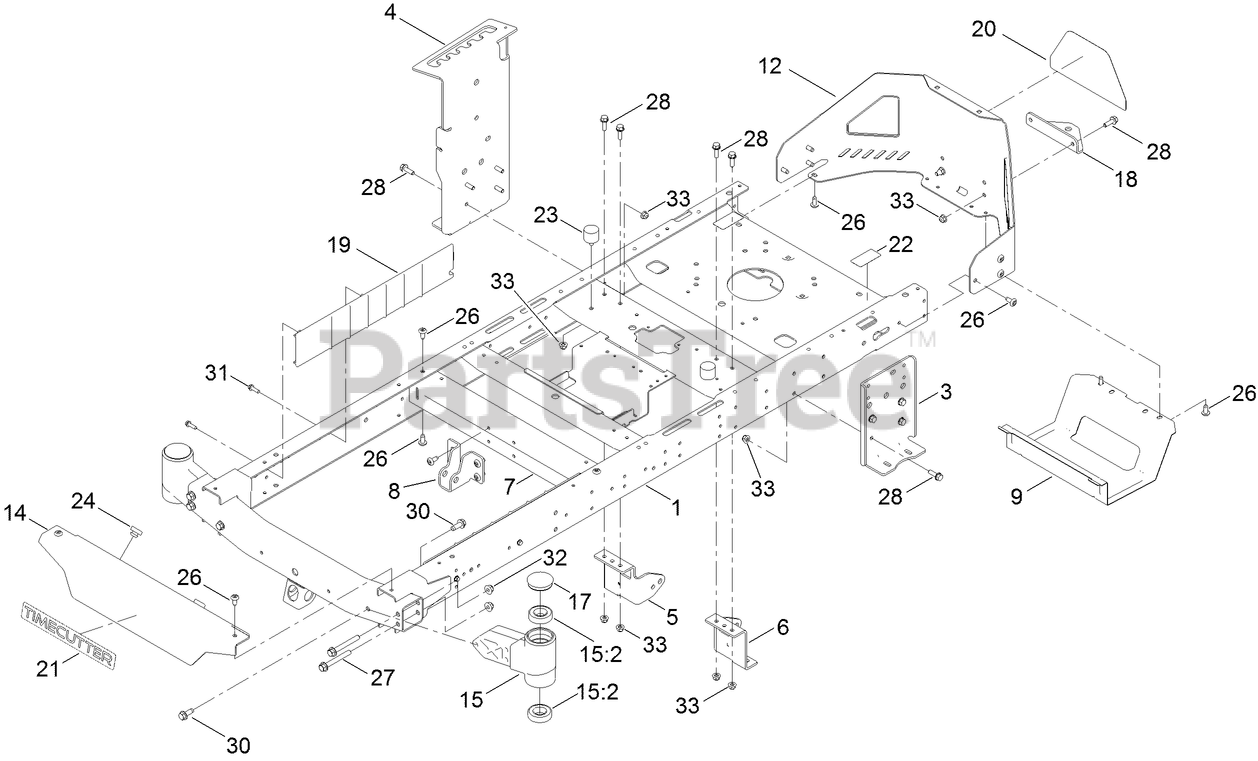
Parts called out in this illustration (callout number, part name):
1	FRAME ASSEMBLY
3	PLATE-MOUNT, HYDRO
4	PLATE-MOUNT HYDRO, RH
5	MOUNT-HYDRO, FRONT (RIGHT)
6	MOUNT-HYDRO, FRONT (LEFT)
7	BRACE-CROSS, LOWER
8	BRACKET-MOUNT DAMPER, LOWER
9	GUARD-MUFFLER
12	GUARD-ENGINE
14	FOOTREST
15	AXLE STUB ASM
15:2	BEARING-BALL
17	CAP-GREASE
18	BRACKET-HITCH
19	GUARD-RAIL
20	DECAL-TIMECUTTER
21	DECAL-TIMECUTTER
22	DECAL-BYPASS
23	BUMPER-RUBBER
24	BUMPER-RUBBER
27	SCREW-HHF
28	SCREW-HHF
30	SCREW-HWH
31	SCREW-PLASTITE, HWH
32	NUT-HF, NI
33	NUT-HF
